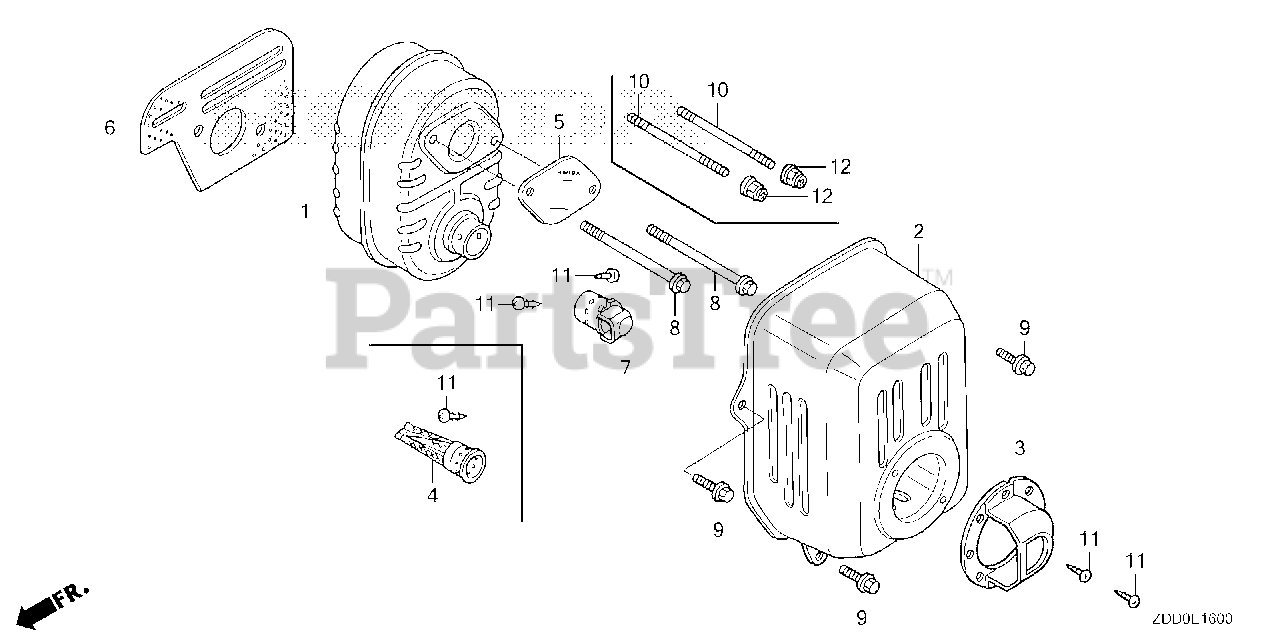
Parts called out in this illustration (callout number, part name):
1	MUFFLER
2	PROTECTOR, MUFFLER
3	CAP, MUFFLER (TO 1207644)
4	ARRESTER, SPARK (TO 1207644)
5	PLATE, ARRESTER NUMBER (TO INSTALL OPTIONAL SPARK ARRESTER)
6	GASKET, MUFFLER
7	DEFLECTOR, MUFFLER (TO 1207644)
8	BOLT, FLANGE (6X79) (CT200)
9	BOLT, FLANGE (6X14)
11	SCREW, TAPPING (4X6) (TO INSTALL OPTIONAL SPARK ARRESTER)
